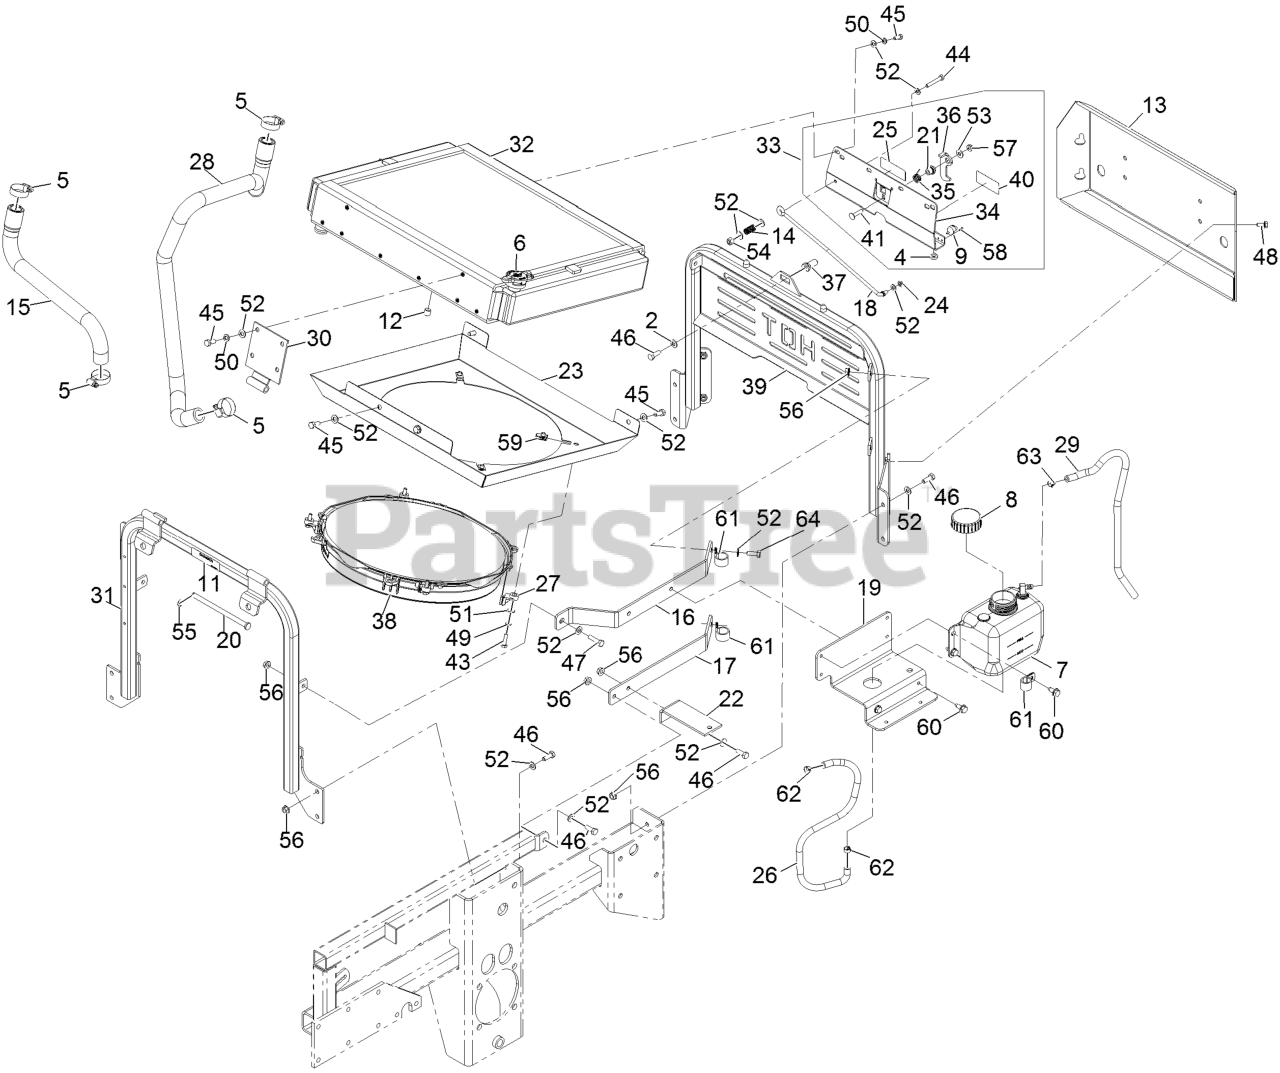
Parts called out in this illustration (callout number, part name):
2	WASHER-SPRING
6	CAP-RADIATOR
7	TANK, OVERFLOW W/CAP
11	DECAL-COVER, MISSING
12	PLUG-PIPE
13	WLD,REAR BUMPER
14	SPRING,LOCK PIN
15	HOSE,RADIATOR UPPER D902(
17	RIB, BOTTOM
18	ROD,PROP
19	BRACKET, BOTTLE-HYDRO TAN
21	BUSHING-LATCH, SEAT
22	BRACKET, HYDRAULIC TANK
23	FAN SHROUD,16
25	DECAL,RADIATOR ASSEMBLY
26	HOSE, .313 I.D.X 25.0 REI
27	MOUNT,FAN
28	HOSE,RADIATOR LOWER D902
29	HOSE, .500 I.D. X 30" EPD
30	WLD,HINGE PLATE
31	ASM, RAD. MOUNT W/ DECALS
32	RADIATOR ASM, AL D902
33	ASM-LATCH PLATE
34	ASM,LATCH PLATE S.O.
35	SPRING,LATCH
36	HOOK,LATCH
37	PIN,LATCH
38	FAN- ELECTRIC
39	Wld, Rear Radiator Mount
40	DECAL-ANTIFREEZE
41	SCREW-CARR
43	SCREW-HH
44	SCREW-HH
45	SCREW-HH
46	SCREW-HH
47	SCREW-HH
48	SCREW-HHF
49	SCREW-HH
50	WASHER-LOCK
51	WASHER-FLAT
52	WASHER-PLAIN
53	WASHER-FLAT
54	NUT-LOCK, NI
59	Nut-Retainer-Panel 1/4-20
60	Screw-HWH 5/16-18 X 3/4 Tf
61	CLIP-LOOM
62	CLAMP-HOSE
63	CLAMP-HOSE
64	SCREW-HH
